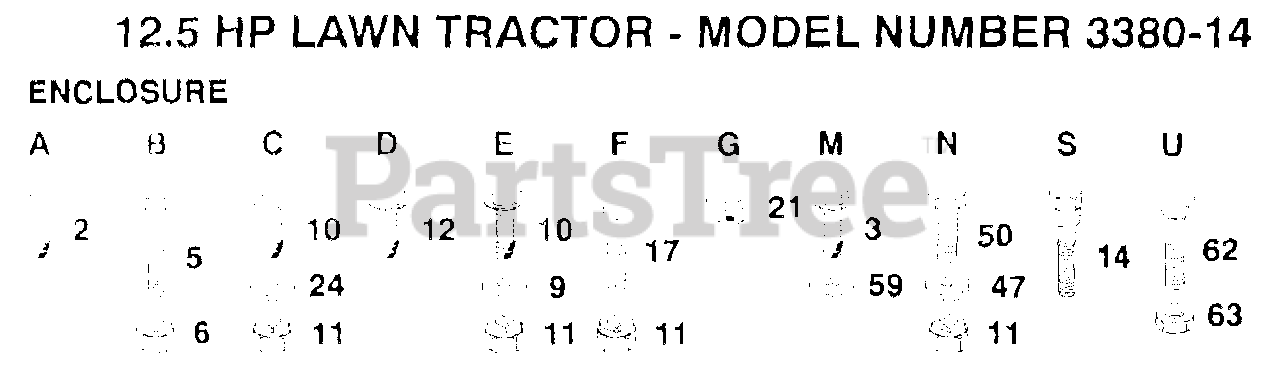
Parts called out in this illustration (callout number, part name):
2	SCREW
3	SCREW GTV
9	WASHER
12	SCREW LT
14	"BOLT,SHOULDER"
17	BOLT
21	PAL NUT LT
24	WASHER
47	WASHER
50	BOLT
59	WASHER
62	BOLT
